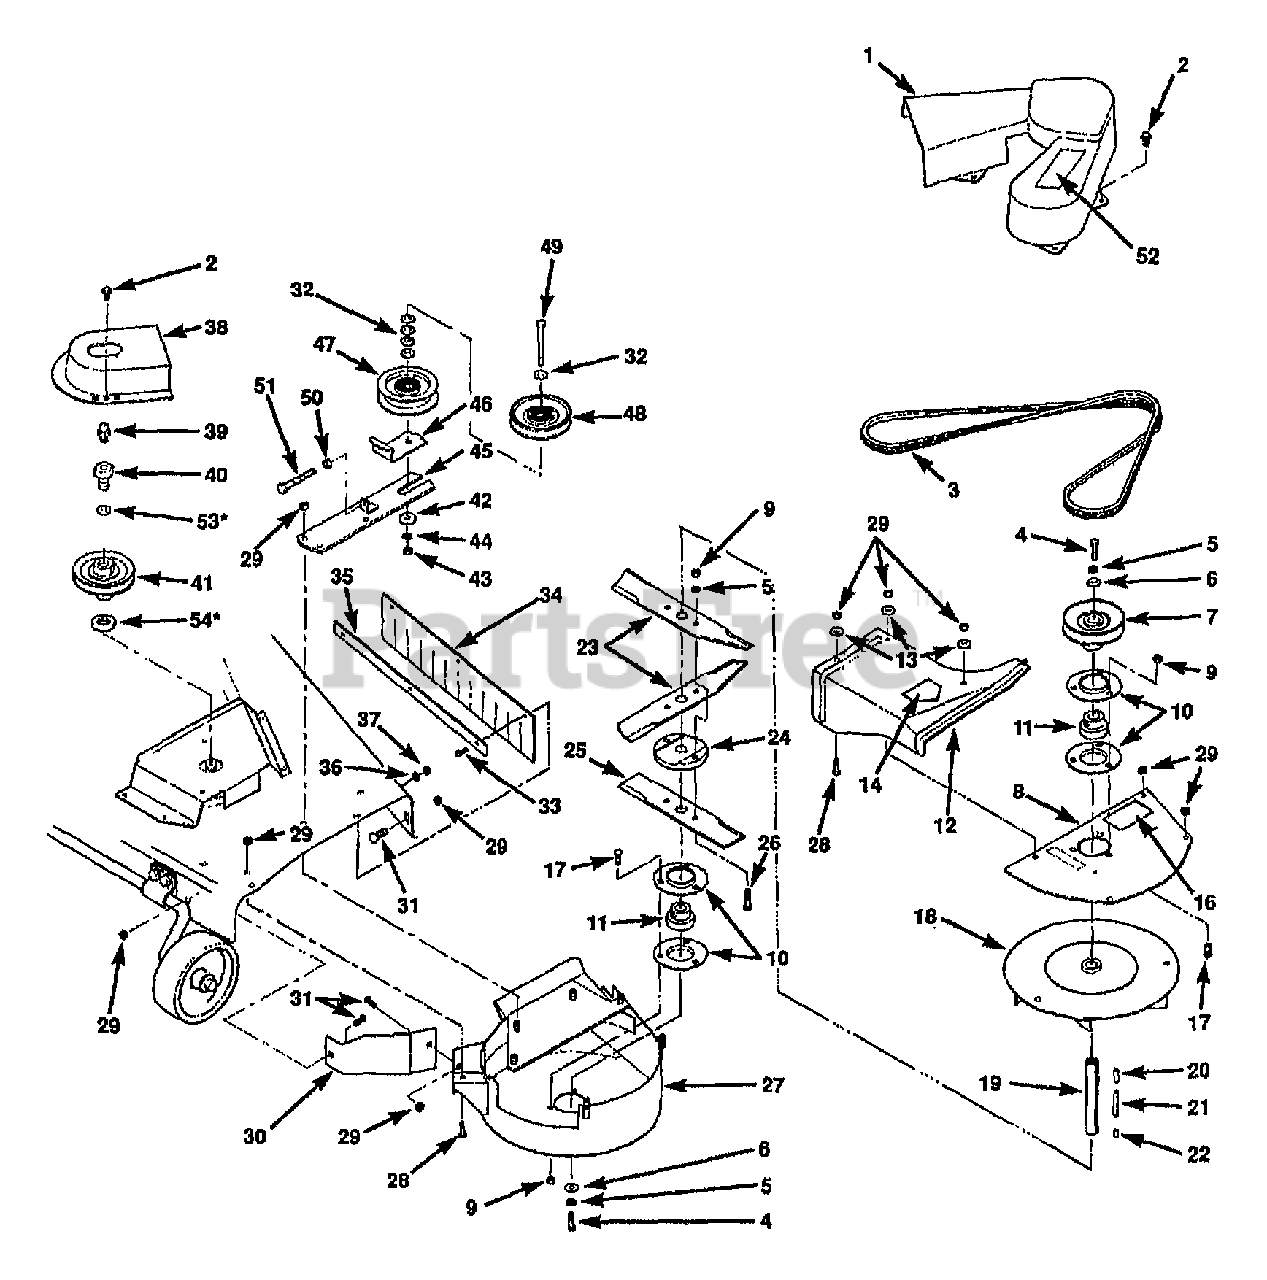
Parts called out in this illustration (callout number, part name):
1	COVER-BELT
2	SCR-THRD FRM 1/4-14X.50
3	BELT-DRIVE
4	SCR-HH 5/16-18X1.0 G5 ZP
5	WASHER-LK .312 ZP
6	WASHER-.312 X 1.378
7	SHEAVE-DRIVEN
8	HOUSING-COVER
9	NUT-TOP/LK 5/16-18 ZP
11	BEARING-BALL
12	DEFLECTR-DISCH W/DECAL
13	WASHER-FLAT 5/16 SAE
14	DECAL-OPEI CAUTION
16	DECAL-BELT INSTALLATION
17	SCR-CARR 5/16-18X.62 G2 ZP
20	KEY-.188 SQ X 1.0
21	KEY-.188 SQ X 2.0
22	KEY .188 SQ X.343
23	BLADE-11.375"
24	HUB-BLADE
25	BLADE-10"
26	SCR-HH 5/16-18X1.25 G5ZP
27	HOUSING-FAN
28	SCR-HFLK 5/16-18X.75 ZP
29	NUT-HFLK 5/16-18 ZP
30	BAFFLE-REAR
31	SCR-CARR 5/16-18X1.0 G2 ZP
32	WASHER-FLAT 3/8 SAE
33	SCR HFLK #10-24X.75 ZP
34	SHIELD-DEFLECTOR
35	STRIP-RETAINER
36	WASHER-LK M10
37	NUT-HEX M10-24
38	GUARD-BELT
39	FITTING-GREASE 1/4-28X2.00
40	LOCK-SHEAVE
41	PULLEY-DRIVE
42	WASHER-FLAT 1.25X.406X.179
43	NUT-HEX 3/8-16 ZP
44	WASHER-LK .375 @ DEPL
45	ASSM-IDLER BRACKET
46	BRKT-ADJUSTMENT
48	PULLEY-IDLER
49	SCR-HHC 3/8-16X3.25
50	NUT-HEX 5/16-18 ZP
51	SCR-HHM 5/16-18X2.75
52	DECAL-IDENTIFICATION
53	SPACER-.625X.406X.179
54	SPACER-1.25X.781X.179
